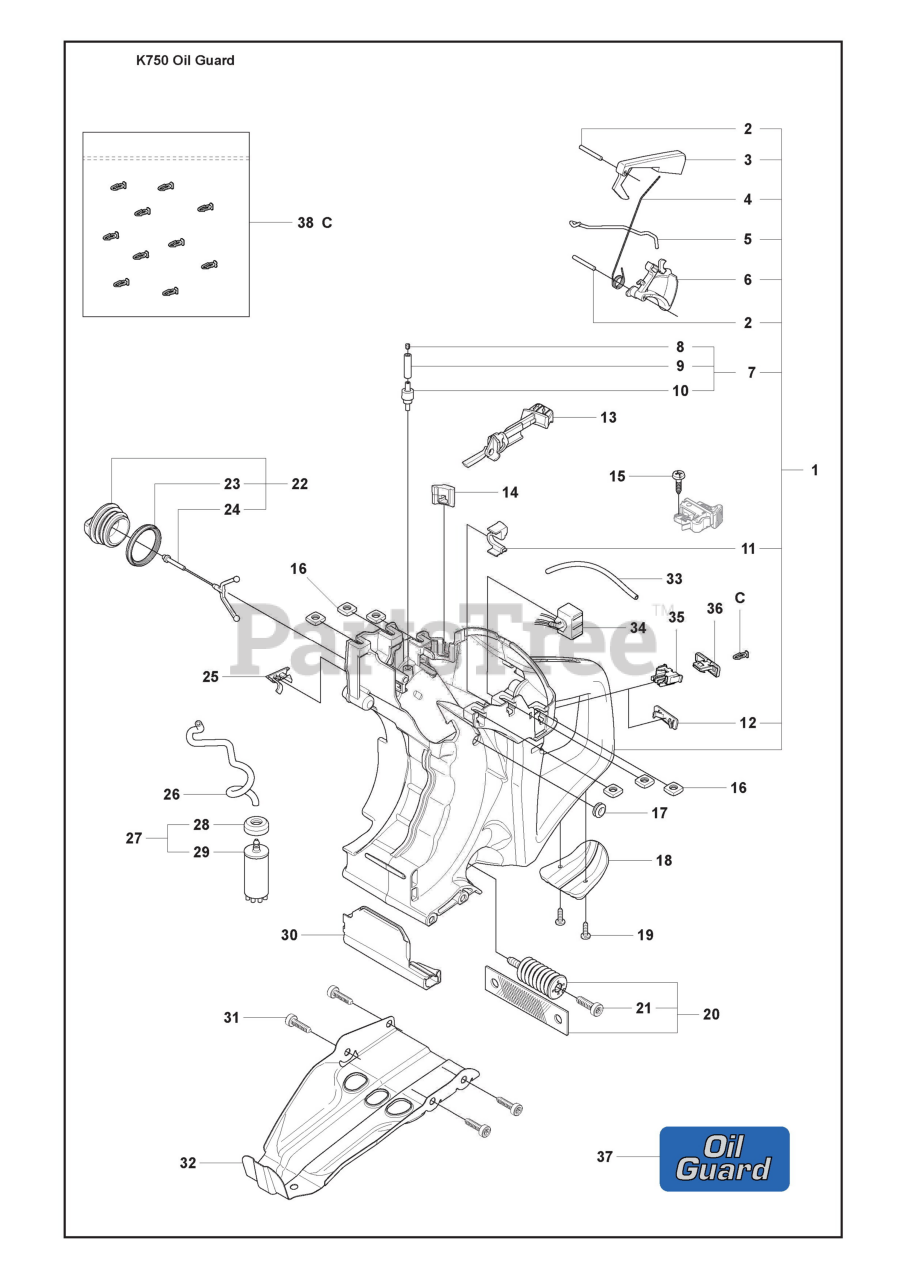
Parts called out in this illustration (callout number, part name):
1	FUEL TANK
2	PARALLEL PIN
3	THROTTLE LOCKOUT
4	SPRING
5	THROTTLE ROD
6	THROTTLE TRIGGER
7	TANK VENT ASSY
8	SINTER PLUG
13	CHOKE CONTROL
17	CABLE GROMMET
18	GROUND SUPPORT
20	AV-ELEMENT
22	TANK CAP ASSY
24	TANK CAP HOLDER
25	CAP
26	FUEL HOSE
27	FUEL FILTER
28	HOSE CLAMP
29	FUEL FILTER
30	HEAT SHIELD
32	BASE PLATE
33	FUEL HOSE
34	ELECTRONIC BOX
35	HOUSING
36	SWITCH
37	LABEL
38	CUP SPRING
